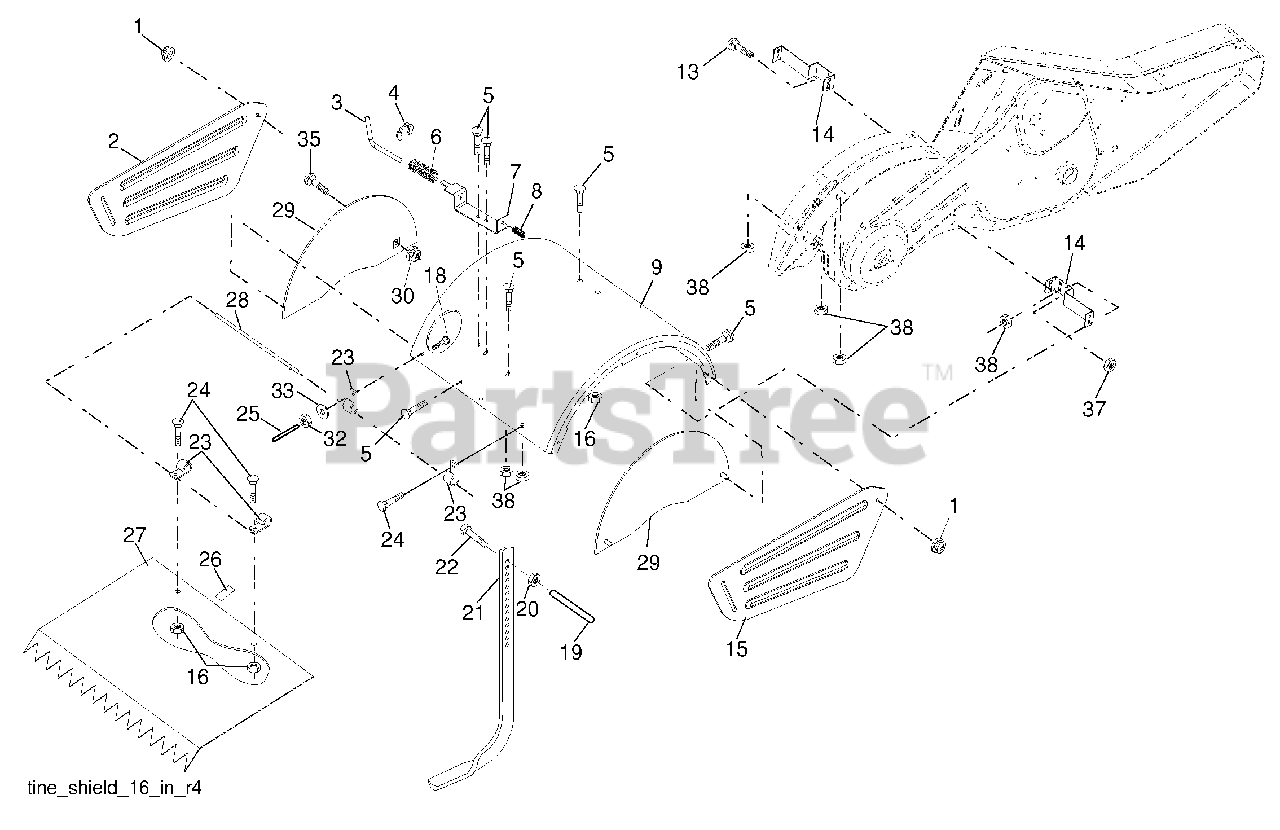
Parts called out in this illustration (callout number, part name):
1	Nut, Lock Hex Flange 5/16-18
2	Shield, Side, Outer L. H.
3	Pin, Stake, Depth
4	Ring, Klip
5	Bolt 5/16-18 x 3/4 ZNC
6	Spring
7	Bracket, Latch
8	Spring, Depth Stake
9	Shield, Tine
13	Bolt, Carriage 5/16-18 x 1-1/4
14	Bracket, Shield Tine
15	Shield, Side, Outer R.H.
16	Nut, Hex Flange 1/4-20 unc
18	Bolt, Carriage 1/4-20 x 1-1/4 Gr. 5
19	Grip
20	Nut, Hex 3/8-16
21	Stake, Depth
22	Bolt, Hex 3/8-16 x 2
23	Hinge
24	Bolt, Carriage 1/4-20 x 1/2 Gr. 5
25	Cap, Vinyl
26	Pad, Idler
27	Shield, Leveling
28	Pin, Hinge
29	Shield, Side
30	Locknut, Flange 5/16-18
32	Nut Fin Hex 1/4-20 unc
33	Washer Lock Hvy Helical 1/4
35	Bolt, Carriage 5/16-18 x 5/8
37	Nut, Lock Hex 5/16-18 unc
38	Nut, Keps 5/16-18 unc
